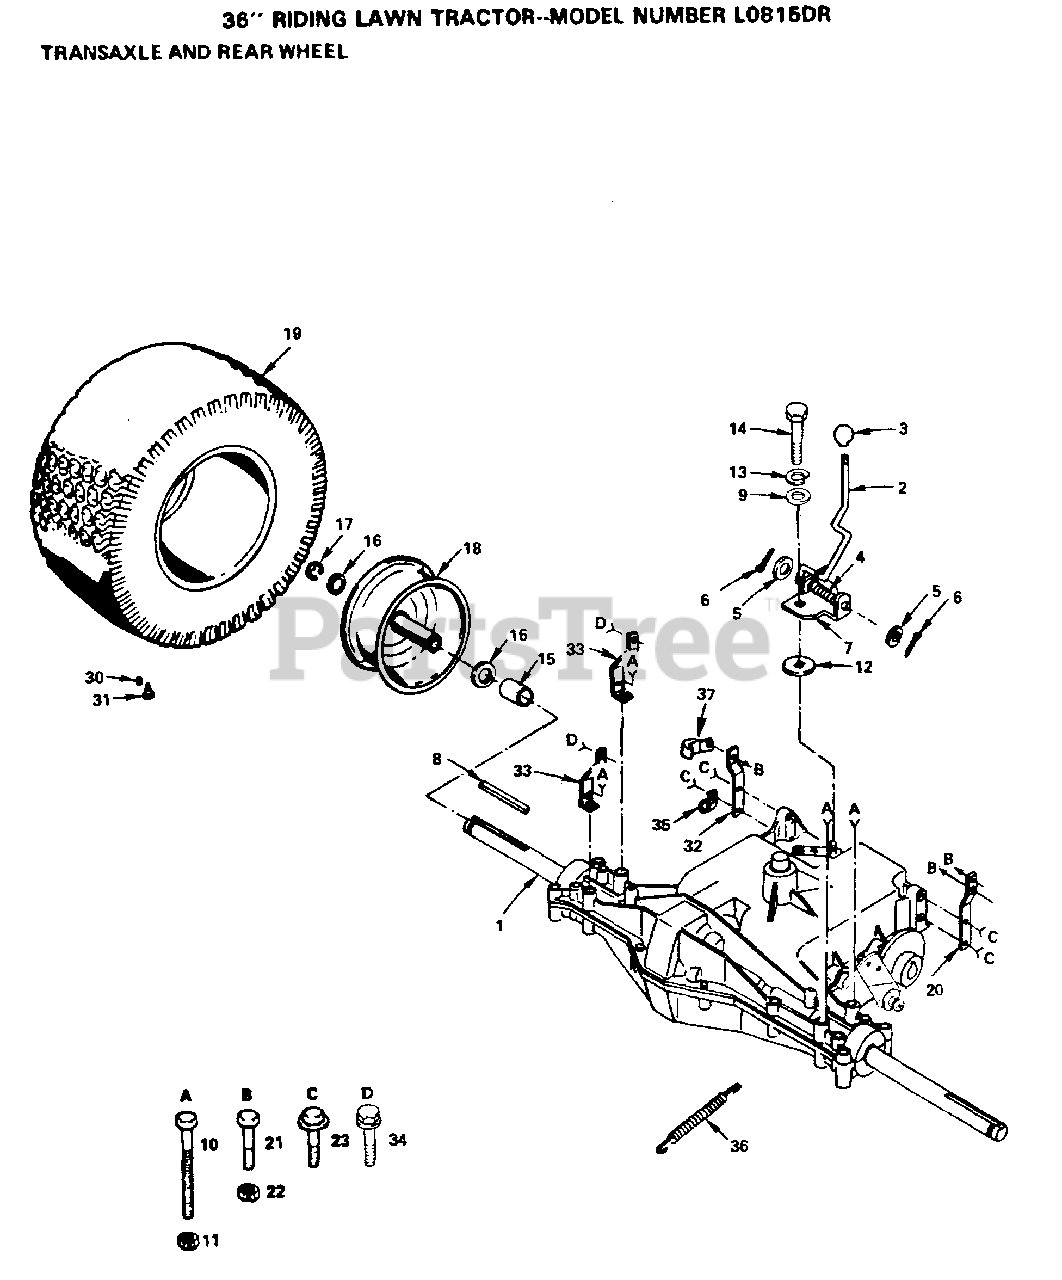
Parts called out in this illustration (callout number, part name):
1	TRANSAXLE ASSY
2	ROD SHIFTER L T
3	CONTROL KNOB LT
4	SPRING LT
5	WASHER
6	PIN COTTER 1/8
7	SHIFT PLATE LT
9	WASHER LT
10	BOLT
12	WASH-SHFT PLT LT
13	LOCKWASHER
15	"SPACER, SPLIT LT"
17	E-RING LT
20	TORQUE STRAP LT
21	BOLT
23	SCREW
30	VALVE CAP
31	VALVE STEM LT
32	TORQUE STRP LH LT
33	STRAP-CHASSIS LT
34	SCREW LT
35	CLIP GTV
36	IDLER SPRING
37	CLIP SB
